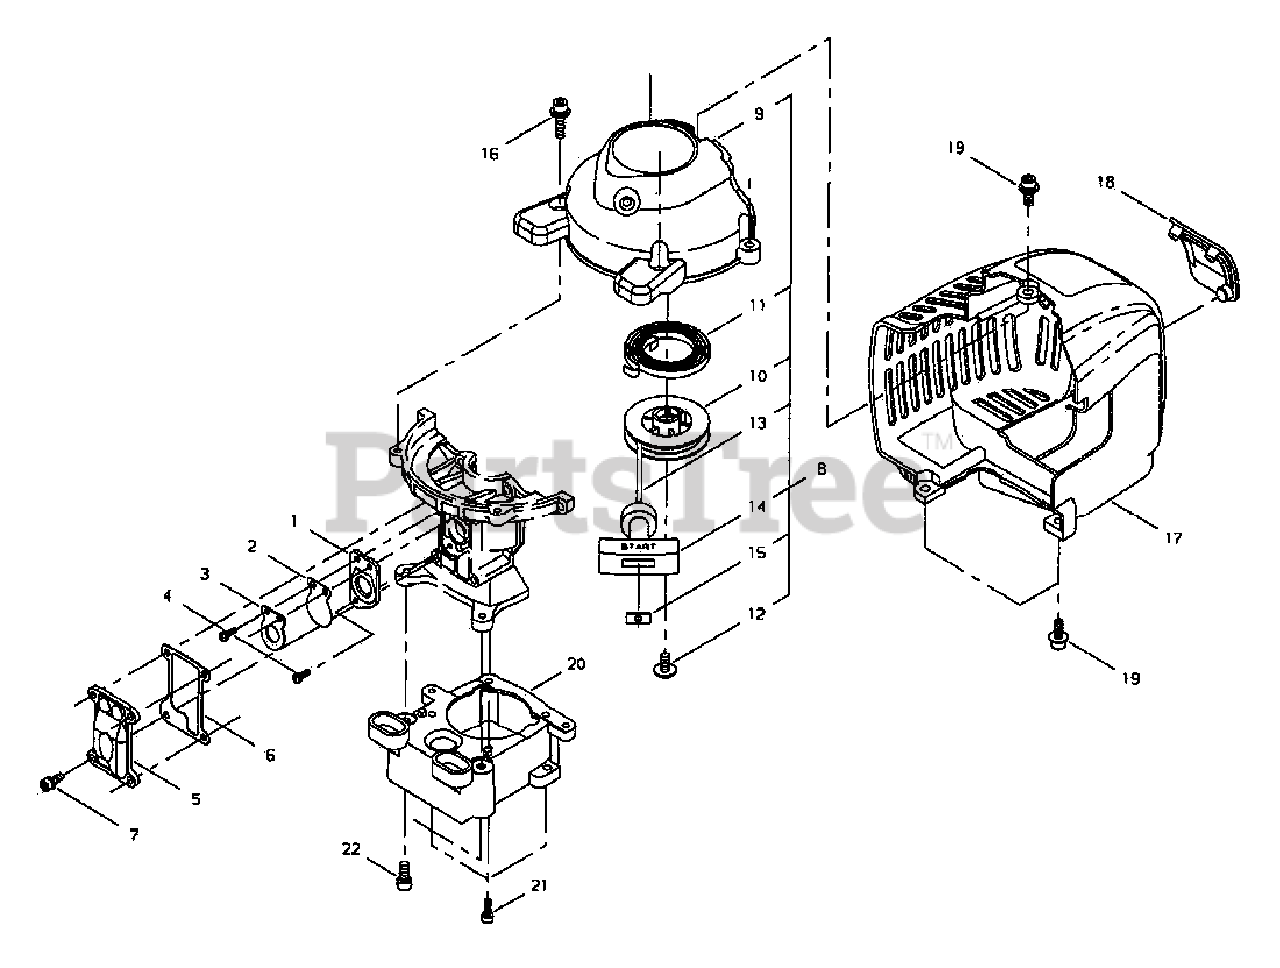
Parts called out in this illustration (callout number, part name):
1	PLATE, REED BACKING
2	VALVE, REED
3	STOP, REED VALVE
4	SCREW M3×10
5	COVER, REED VALVE
6	GASKET, REED VALVE
7	BOLT M4×12
8	STARTER ASSY, RECOIL
9	CASE, RECOIL STARTER
10	REEL, ROPE
11	SPRING, RECOIL
12	SCREW 5
13	ROPE, STARTER
14	GRIP, STARTER
15	RETAINER, ROPE
16	BOLT, ADHESIVE M5×20
17	COVER, ENGINE
18	GROMMET
19	BOLT, ADHESIVE M5×14
20	ADAPTOR, GEAR CASE
21	BOLT 4×12
22	BOLT 5×12
